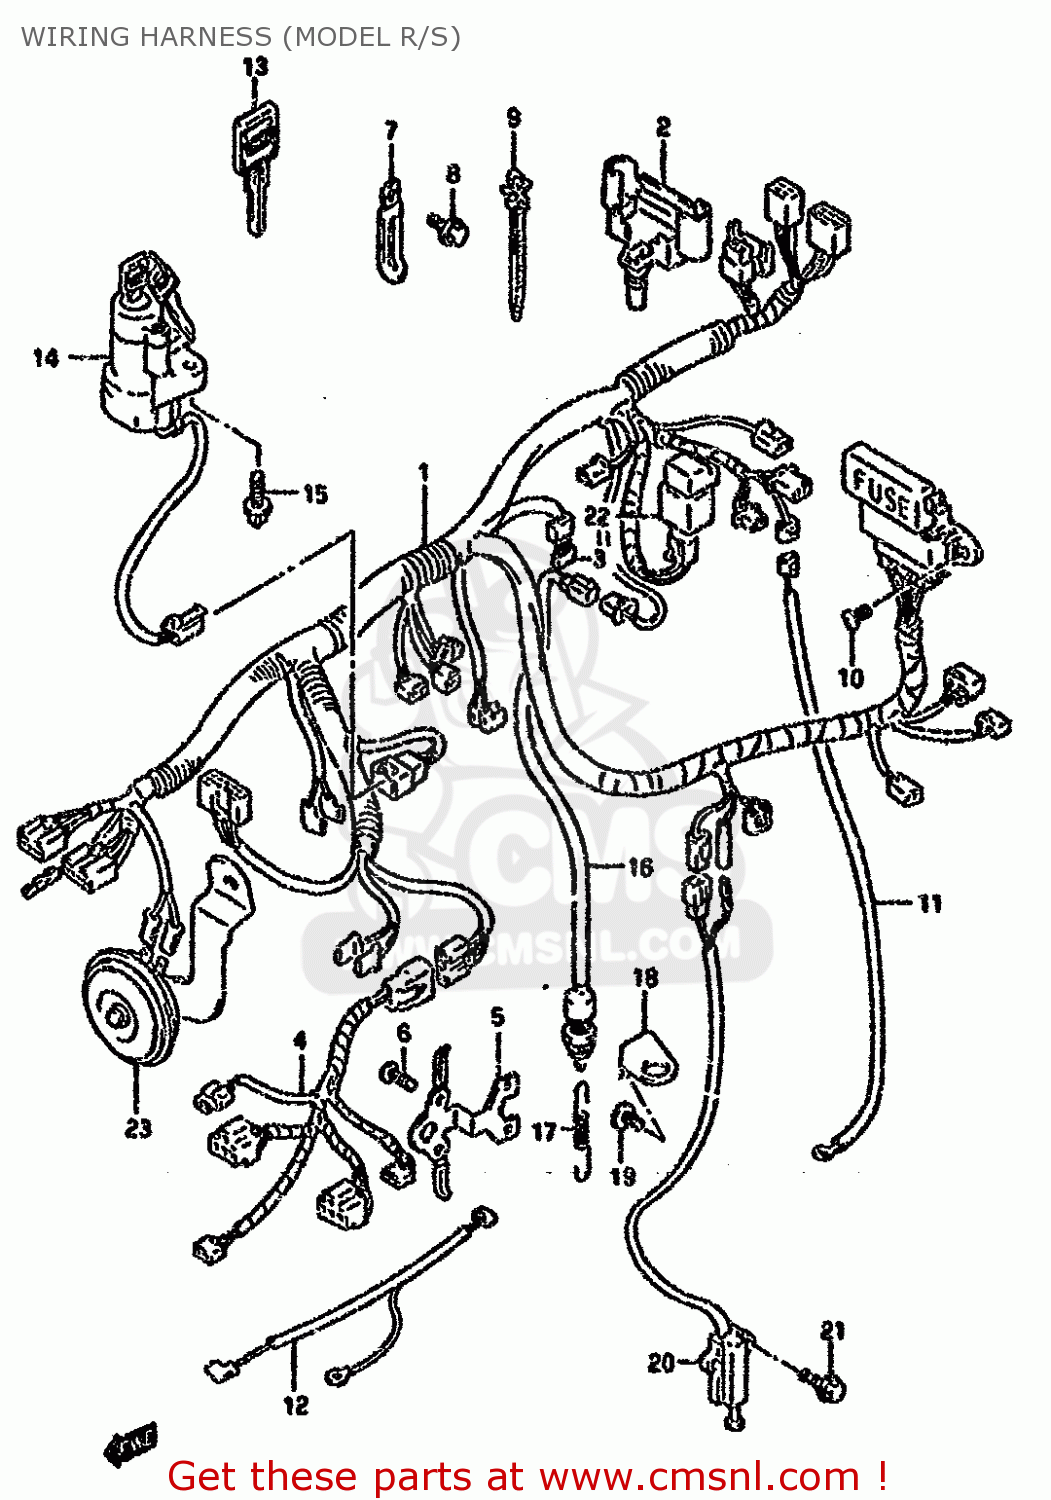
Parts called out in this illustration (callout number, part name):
1	HARNESS,WIRING NO.1
2	CAP,STARTER RELAY
3	DIODE(STANLEY DE8804)
4	HARNESS,WIRING NO.2
5	HOLDER COMP,COUPLER
6	SCREW 5X8
7	CLAMP
8	BOLT
9	CLAMP(L:90)
10	SCREW 6X12
11	WIRE,WATER TEMPERATURE GAUGE
12	WIRE,OIL PRESSURE SWITCH LEAD
13	KEY,BLANK
14	SWITCH ASSY,IGNITION
15	BOLT M8X20
16	SWITCH ASSY,STOP LAMP
17	SPRING
18	BRACKET,STOP LAMP SWITCH
19	SCREW(6X12)
20	SWITCH ASSEMBLY,SIDE STAND
21	BOLT
22	SCREW(6X12)
23	HORN ASSY, HIGH
24	BOLT 6X20
25	RELAY ASSEMBLY
26	HORN ASSY, HIGH
